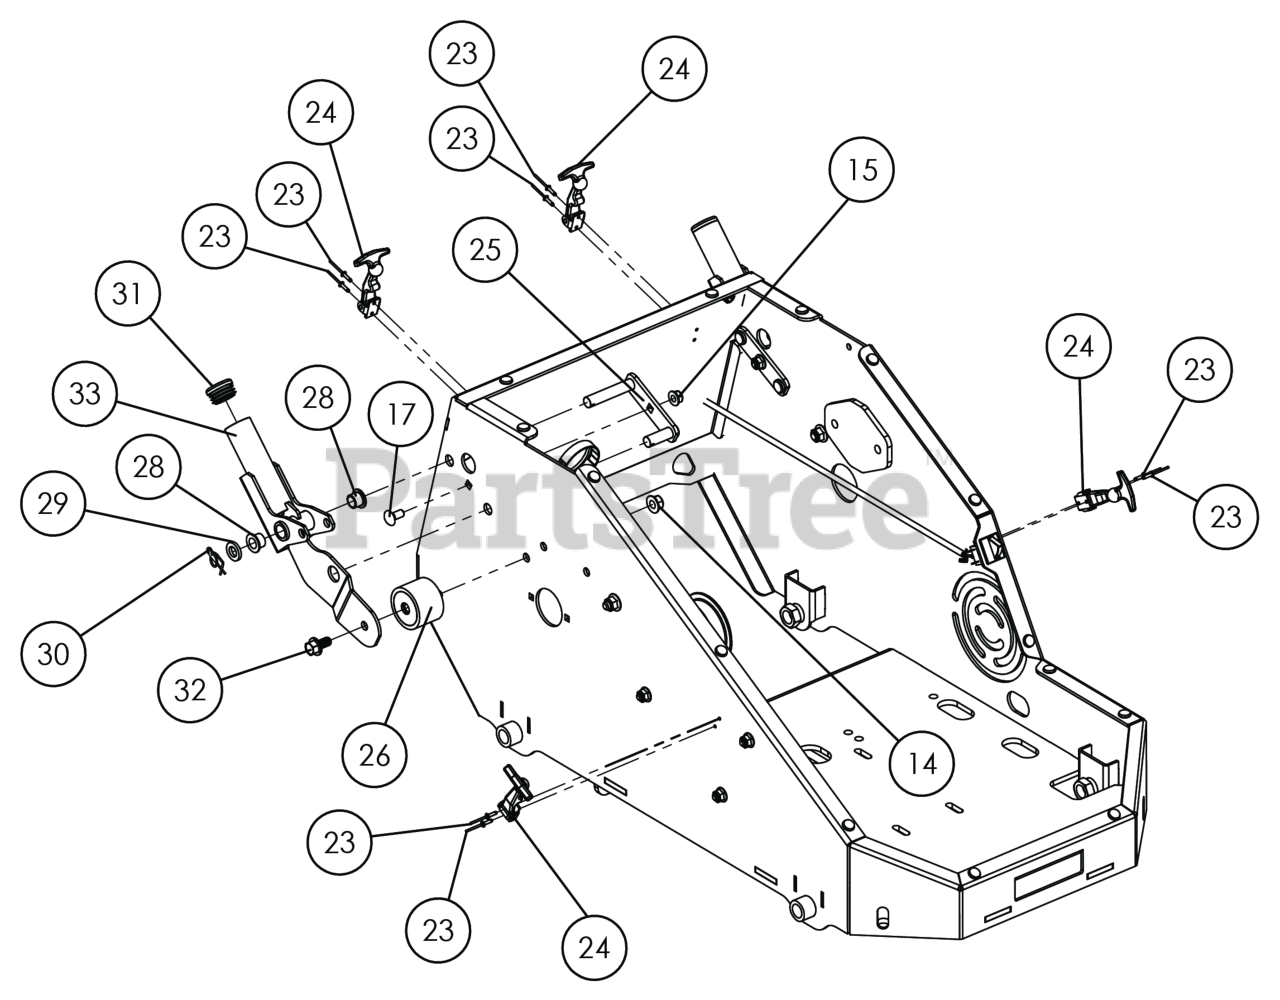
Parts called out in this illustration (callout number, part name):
14	NUT-HEX-NYLK, FLG .375"-16 ZP
15	NUT-HEX-NYLK, FLG .3125-18 ZP
17	BOLT CARRIAGE 5/16"-18 X 3/4" ZP
23	STAINLESS RIVET, 1/8 DIA X 1/4
24	SEE: LATCH DRAW RUBBER 381003-01 & LATCH CLEAT 381003-02
25	WA, ISO MOUNT
26	ISOLATOR, VIBRATION HANDLE SC181H
28	BUSHING .500" ID
29	WSHR-STL,FLT .500"X.875"X.134" MAB ZP
30	RING, RUE .500"
31	PLUG TUBE INSERT 1.25" O.D.
32	SER HEX WASHER 3/8" - 16
33	WA, REVOLVER RH
